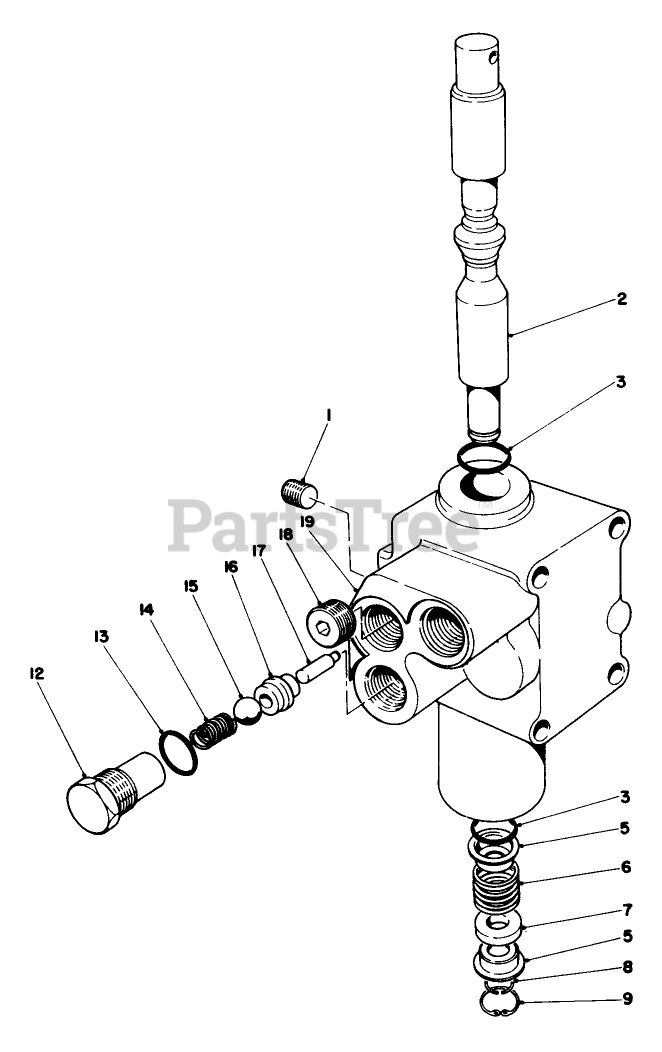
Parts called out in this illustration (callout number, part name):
2	SPOOL
3	O-RING
5	RETAINER
6	SPRING
7	FLOAT SPACER
8	RING-SNAP
9	RING-SNAP
13	O-RING
14	SPRING
16	SEAT-VALVE
